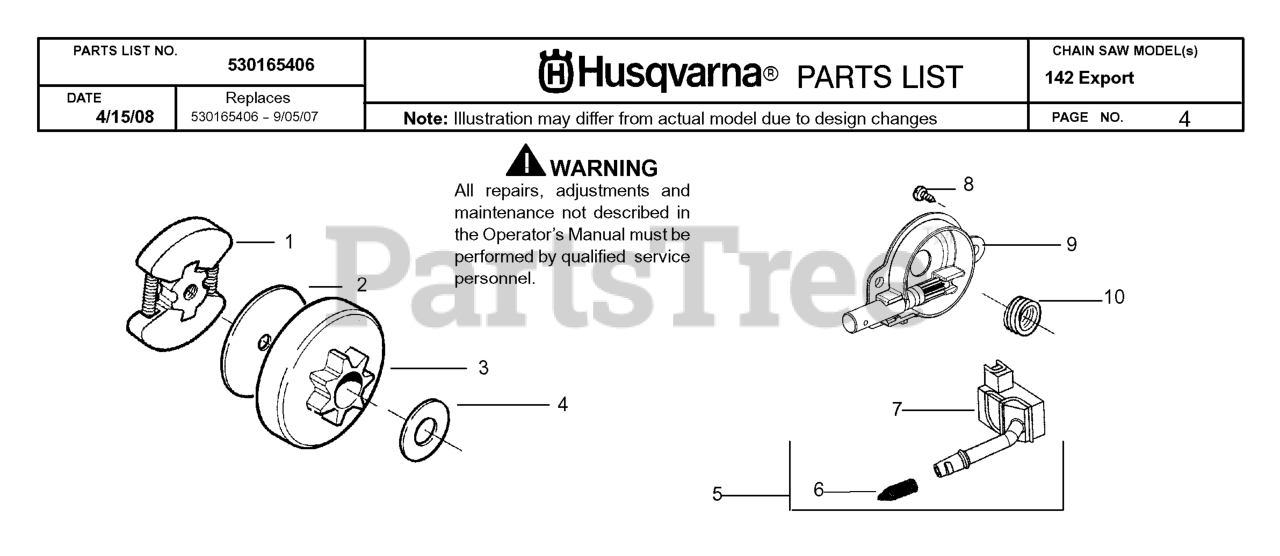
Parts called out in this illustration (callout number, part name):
1	CLUTCH ASSEMBLY
2	FRICTION DISC,CLUTCH 36/41
3	CLUTCH DRUM ASSY
3	ASSY CLUTCH DRUM .325"
4	THRUST WASHER
5	OIL PICKUP
6	SCREEN/FILTER
9	OILER ASS'Y 36/41
10	OILER GEAR 36/41
